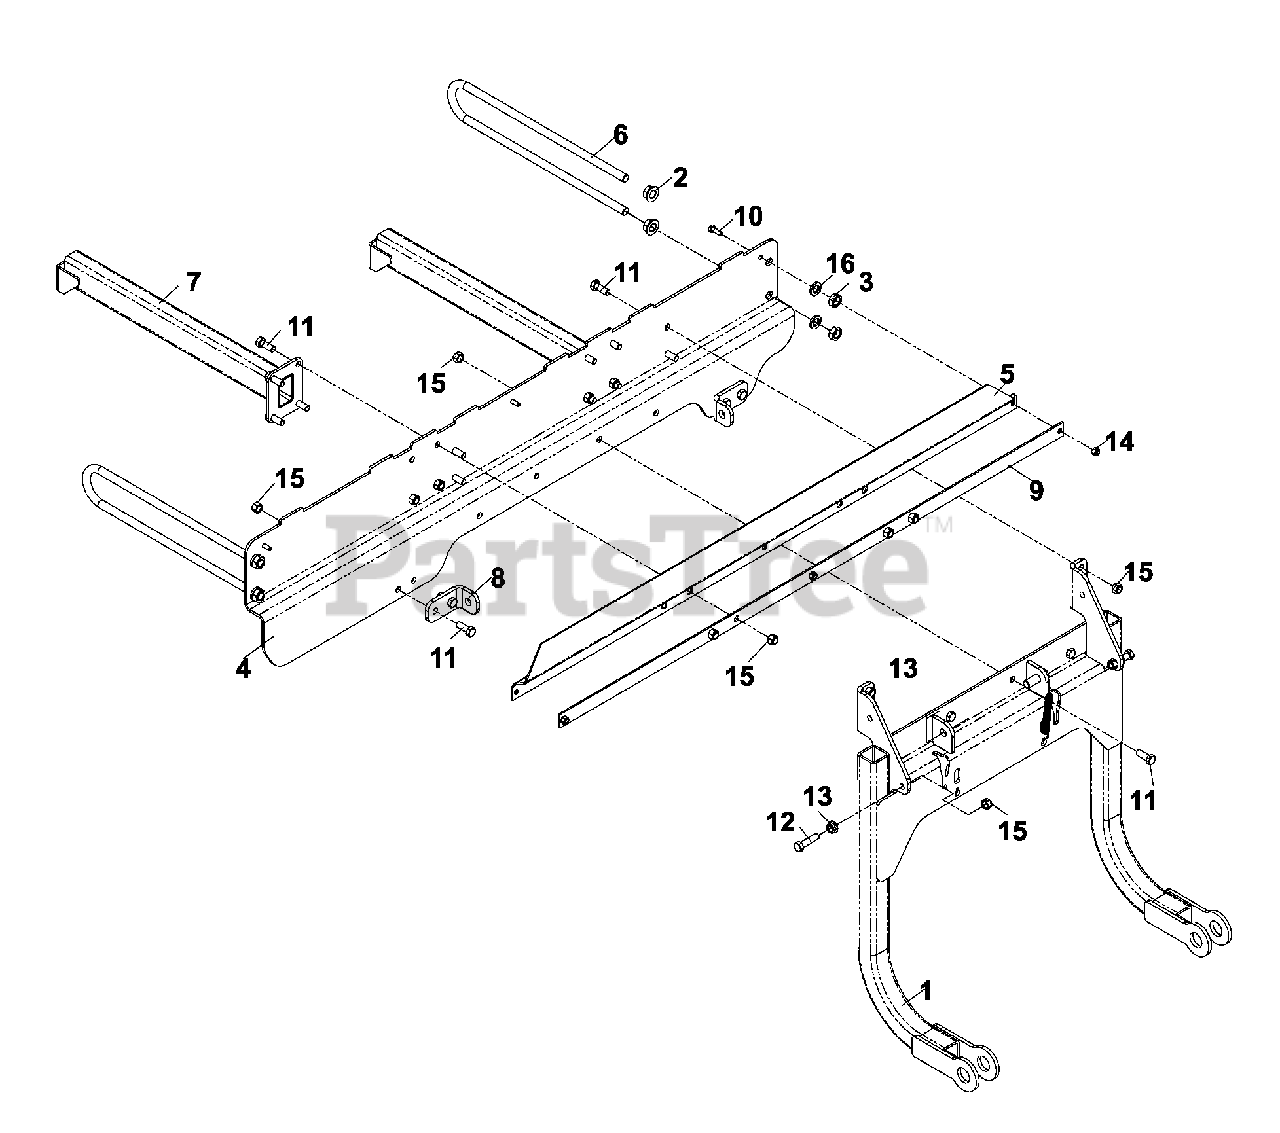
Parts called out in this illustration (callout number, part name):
1	HITCH WELDMENT
2	NUT 1/2-13 HEX
3	NUT 1/2 HEX JAM
4	MOUNT Z BRACE
5	SEAL, RUBBER
6	SUPPORT, OUTER
7	SUPPORT ARM WELDMENT
8	BRACKET, SUPPORT
9	SEAL STRAP
10	HCS 1/4C X 3/4 HCS
11	HCS 3/8C X 1
12	HCS 3/8C X 1 1/2
13	NUT 3/8C WHIZ
14	NUT 1/4-20 NYLOC
15	NUT 3/8-16 NYLOC
16	WASHER 1/2" SPLIT LOCK
